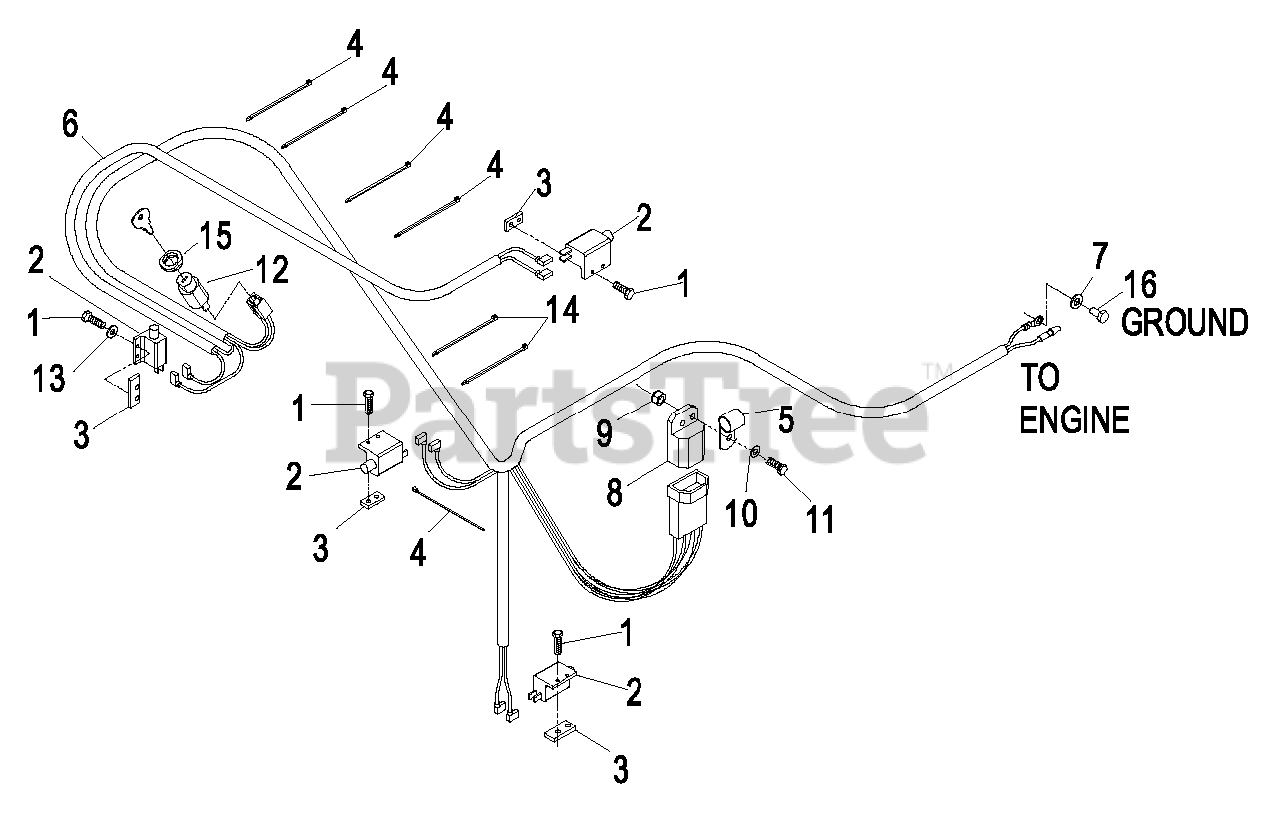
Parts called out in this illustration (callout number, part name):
1	SCREW-PPH
2	SWITCH-OPEN, NORMALLY
3	PLATE-TAPPED
4	TIE-CABLE
5	CLIP-LOOM
6	HARNESS,WIRING KA PULL ST
7	WASHER-PLAIN
8	MODULE-INTERLOCK
9	NUT-LOCK, NI
10	WASHER-FLAT
11	SCREW-HH
12	SWITCH & KEY (INCLUDES NU
13	WASHER-FLAT
14	TIE-PLASTIC
15	NUT-SWITCH, IGNITION
16	SCREW-HH
